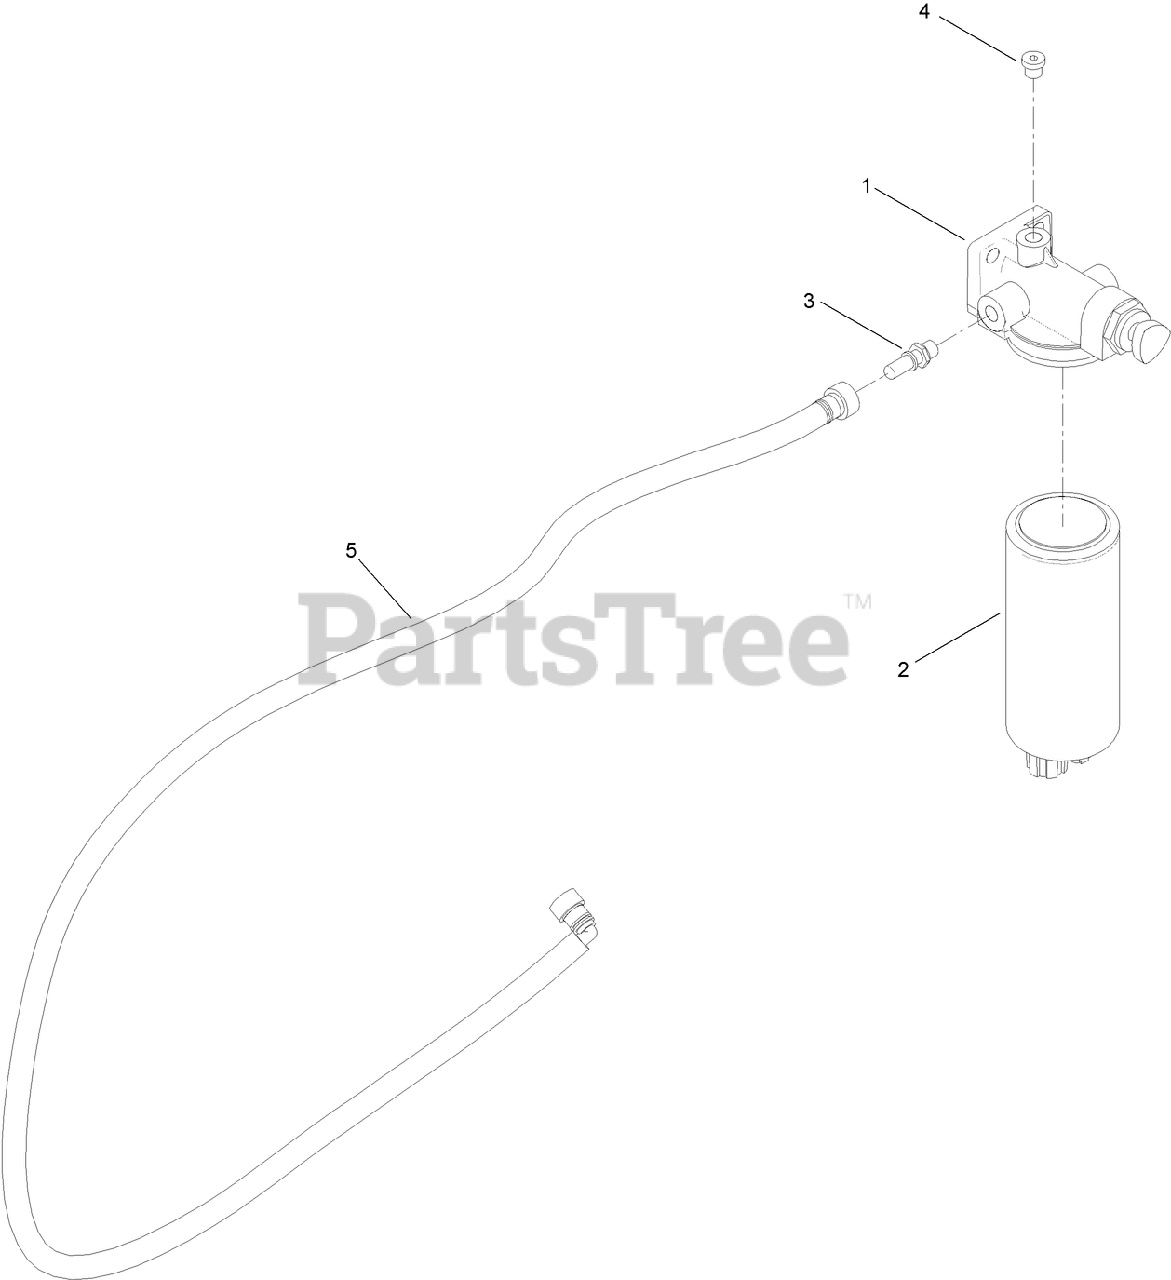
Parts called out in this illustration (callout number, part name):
1	HEAD-FILTER, FUEL
2	FILTER-FUEL
3	FITTING-FUEL
5	HOSE ASM
